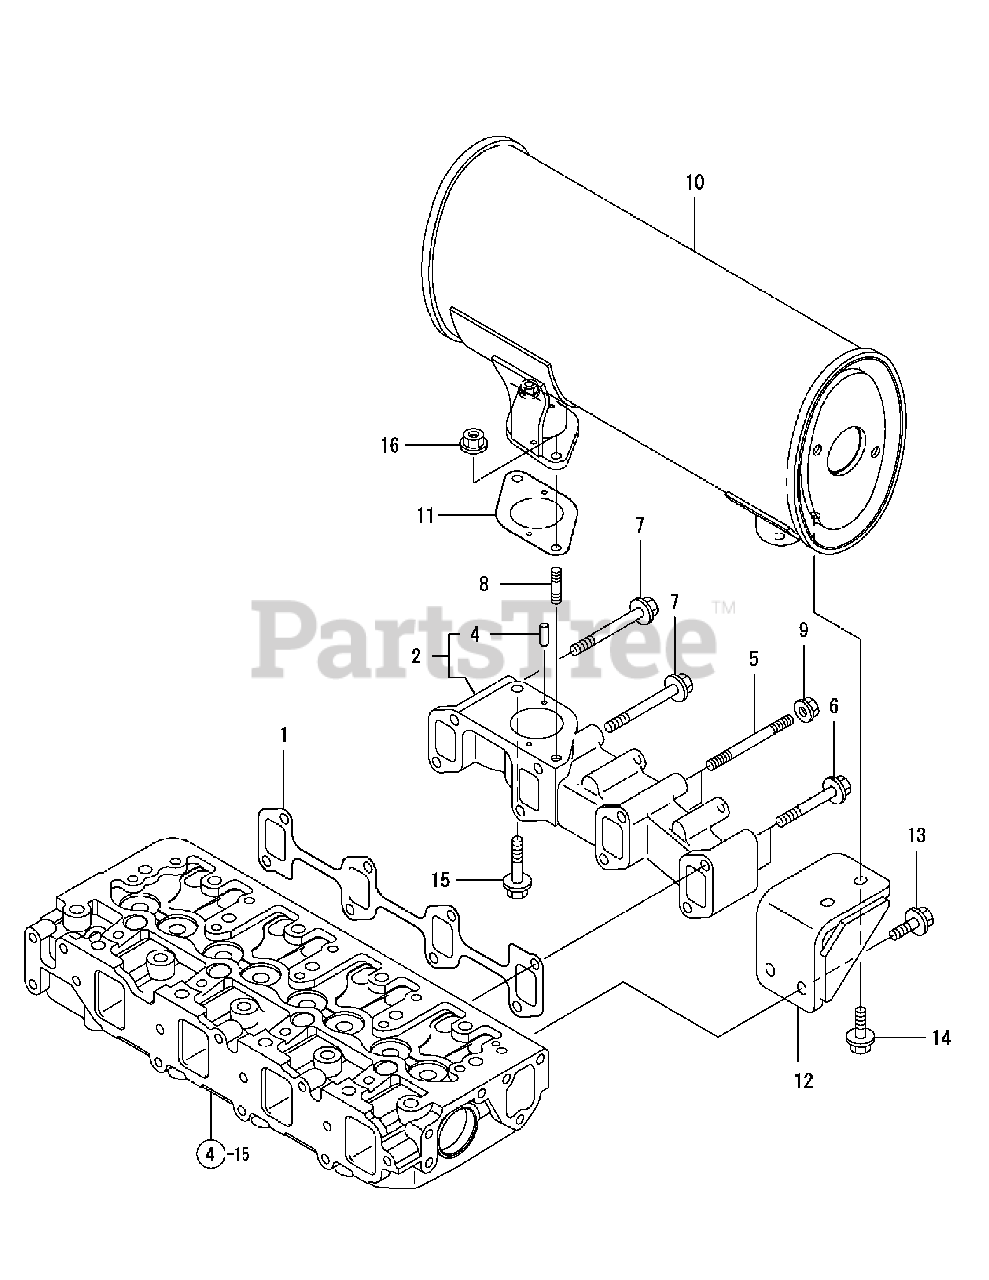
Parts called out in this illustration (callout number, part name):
1	GASKET, EXH.MANIFOLD
2	MANIFOLD CMP,EXHAUST
4	SPRING PIN 4X12
11	PACKING,SILENCER GSK
12	STAY, SILENCER
15	BOLT M 8X 40 PLATED
